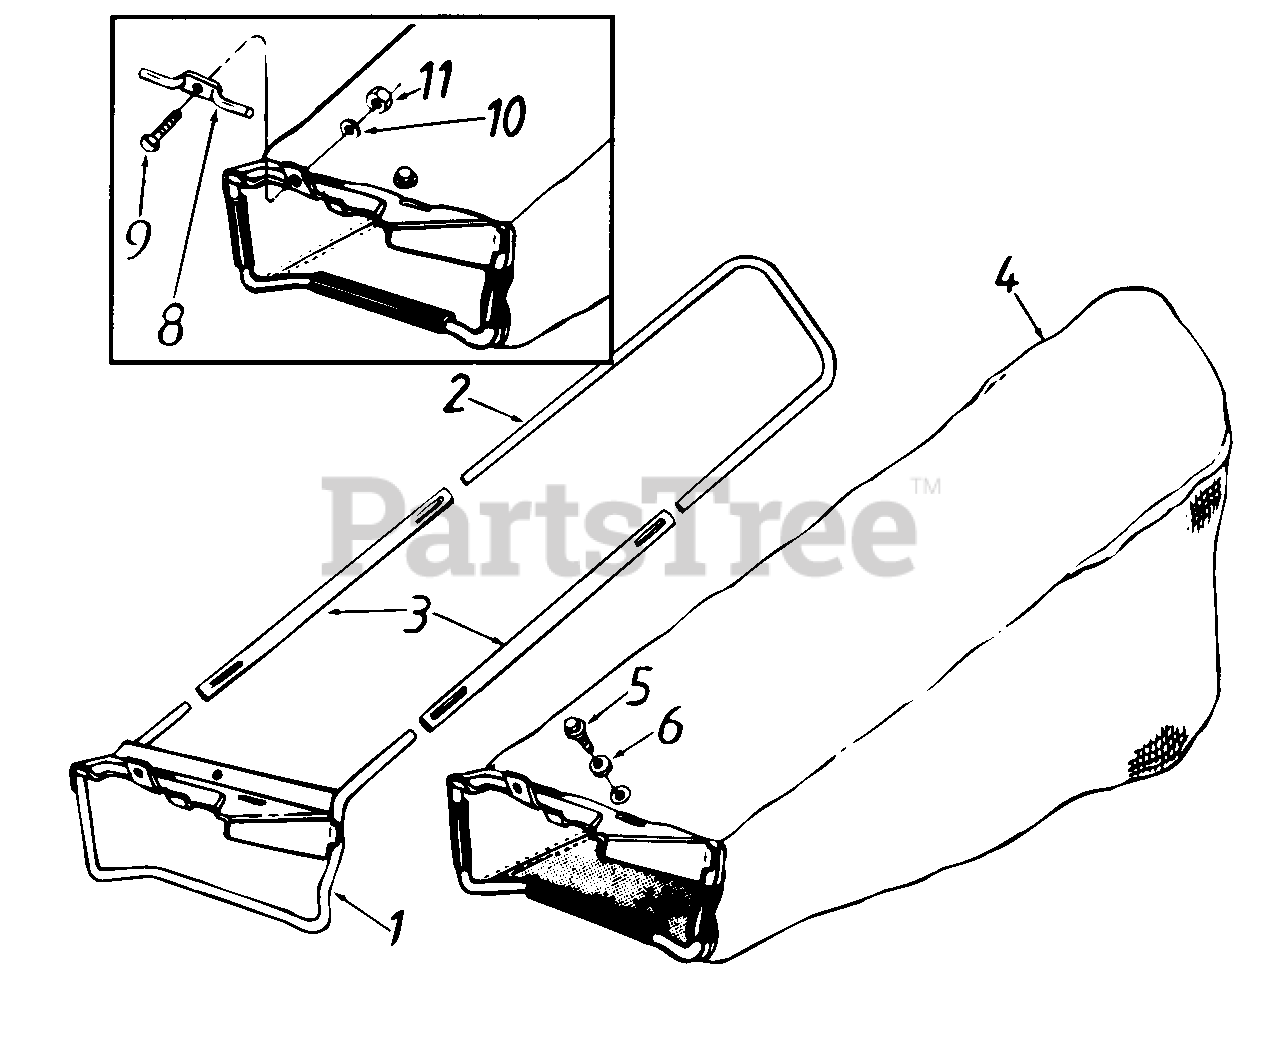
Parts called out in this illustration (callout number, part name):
4	Grass Bag
5	Hex Wash. Hd. TT-Tap Scr. 1/4-20 x 5" Lg.
6	Bell-Wash. 1/4" I.D.
8	Grass Bag Hood
9	Hex Bolt 1/4-20 x .62" Lg.
10	L-Wash. 1/4" I.D.
11	Hex Nut 1/4-20 Thd.
